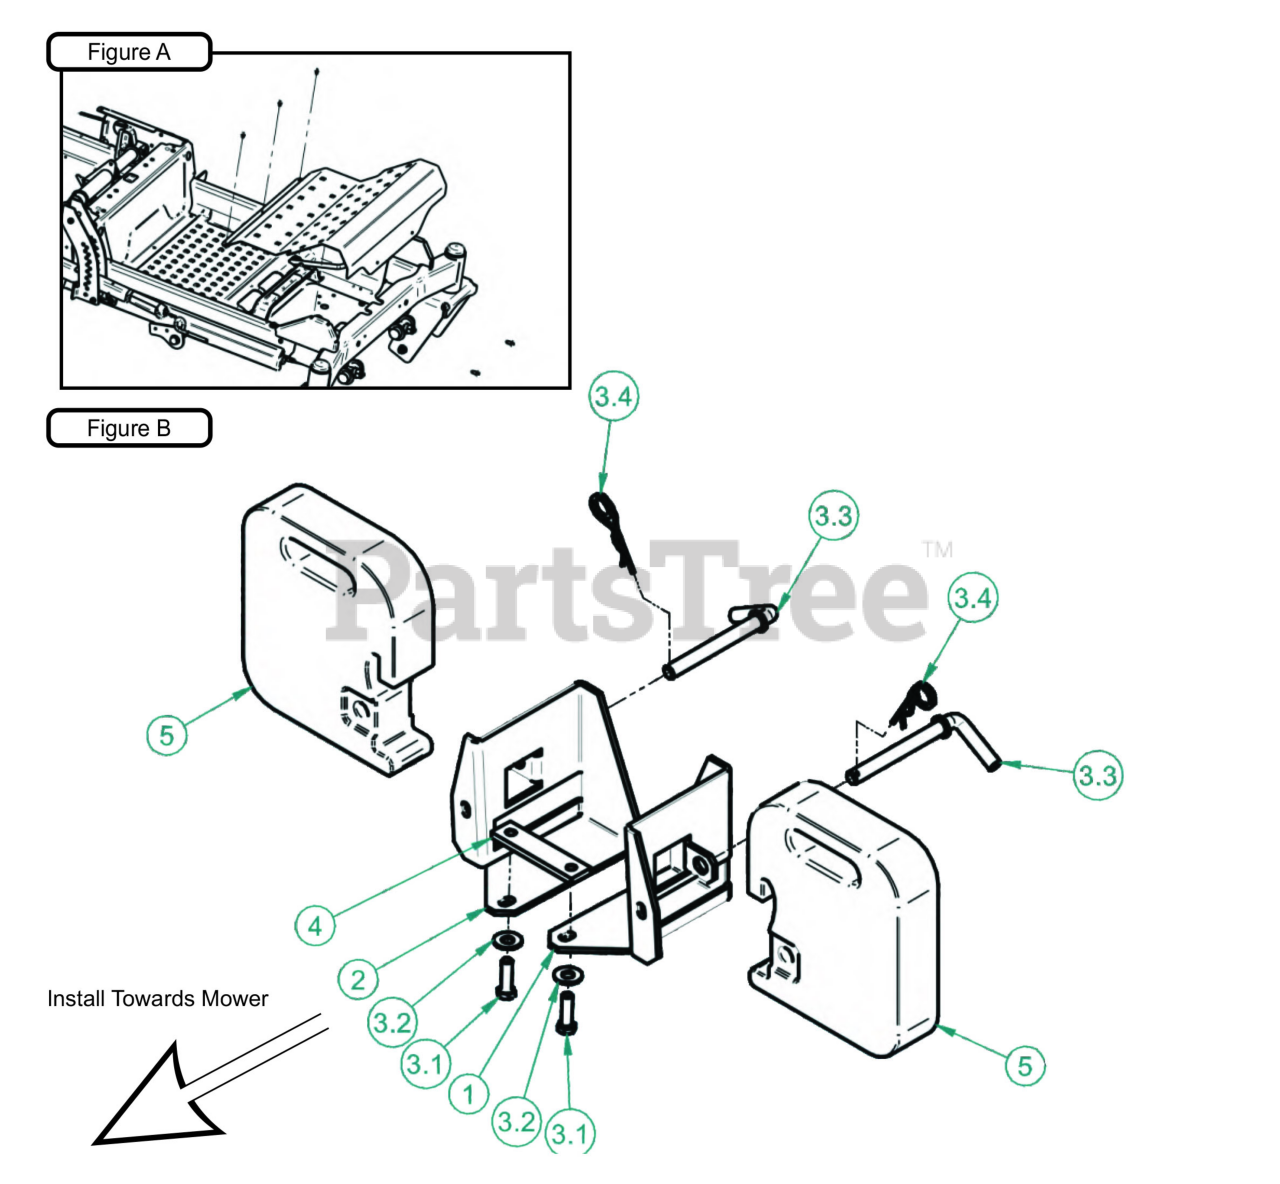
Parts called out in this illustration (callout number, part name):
1	RT WEIGHT MOUNTING PLATE
2	LT WEIGHT MOUNTING PLATE
3	HARDWARE FOR WEIGHT KIT
3.1	BOLT-HEX 3/8-16 X
3.2	FLAT WASHER 3/8
3.3	Not Serviceable/ Order Complete Assembly
3.4	Not Serviceable/ Order Complete Assembly
4	WEIGHT KIT HARDWARE BAG
5	SUITCASE WEIGHT 28#
